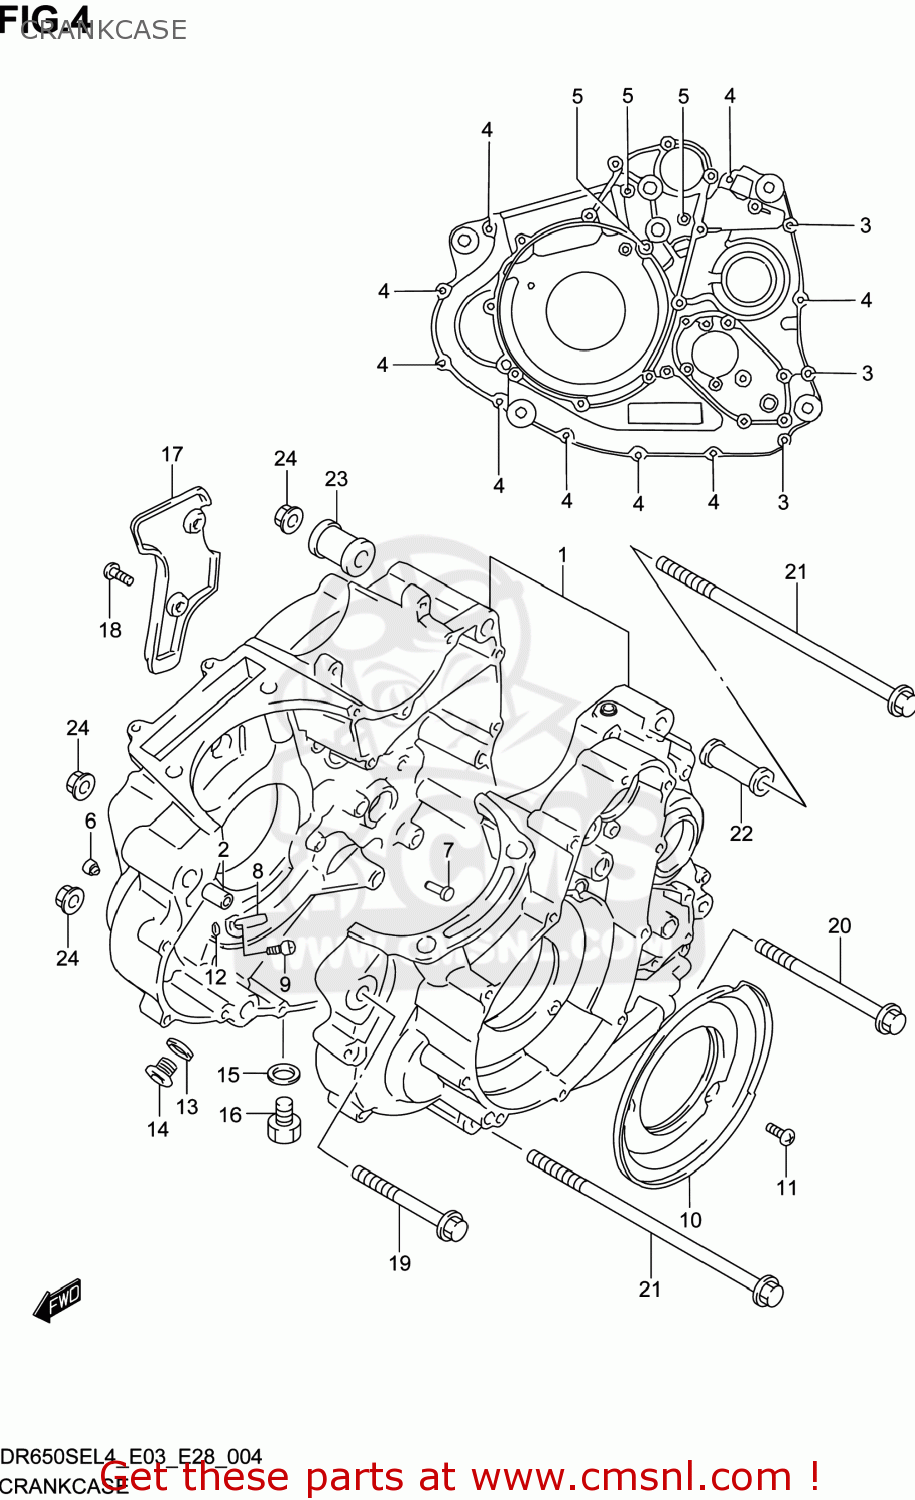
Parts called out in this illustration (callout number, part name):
1	CRANKCASE SET
2	PIN
3	BOLT
4	BOLT
5	BOLT
6	JET,OIL GALLERY
7	RIVET
8	JET,PISTON COOLING
9	BOLT(6X12)
10	SEPARATOR,CRANKCASE OIL
11	SCREW
12	O RING(D:1.2,ID:4)
13	GASKET(13.8X18.8X4.8) (NAS)
14	PLUG,14X12
15	GASKET(13.8X18.8X4.8) (NAS)
16	PLUG(14X12)
17	COVER,BREATHER
18	SCREW
19	BOLT(10X100)
20	BOLT(10X130)
21	BOLT(10X235)
22	SPACER,ENGINE MOUNT(L:65)
23	SPACER,ENGINE MOUNT(L27)
24	NUT
